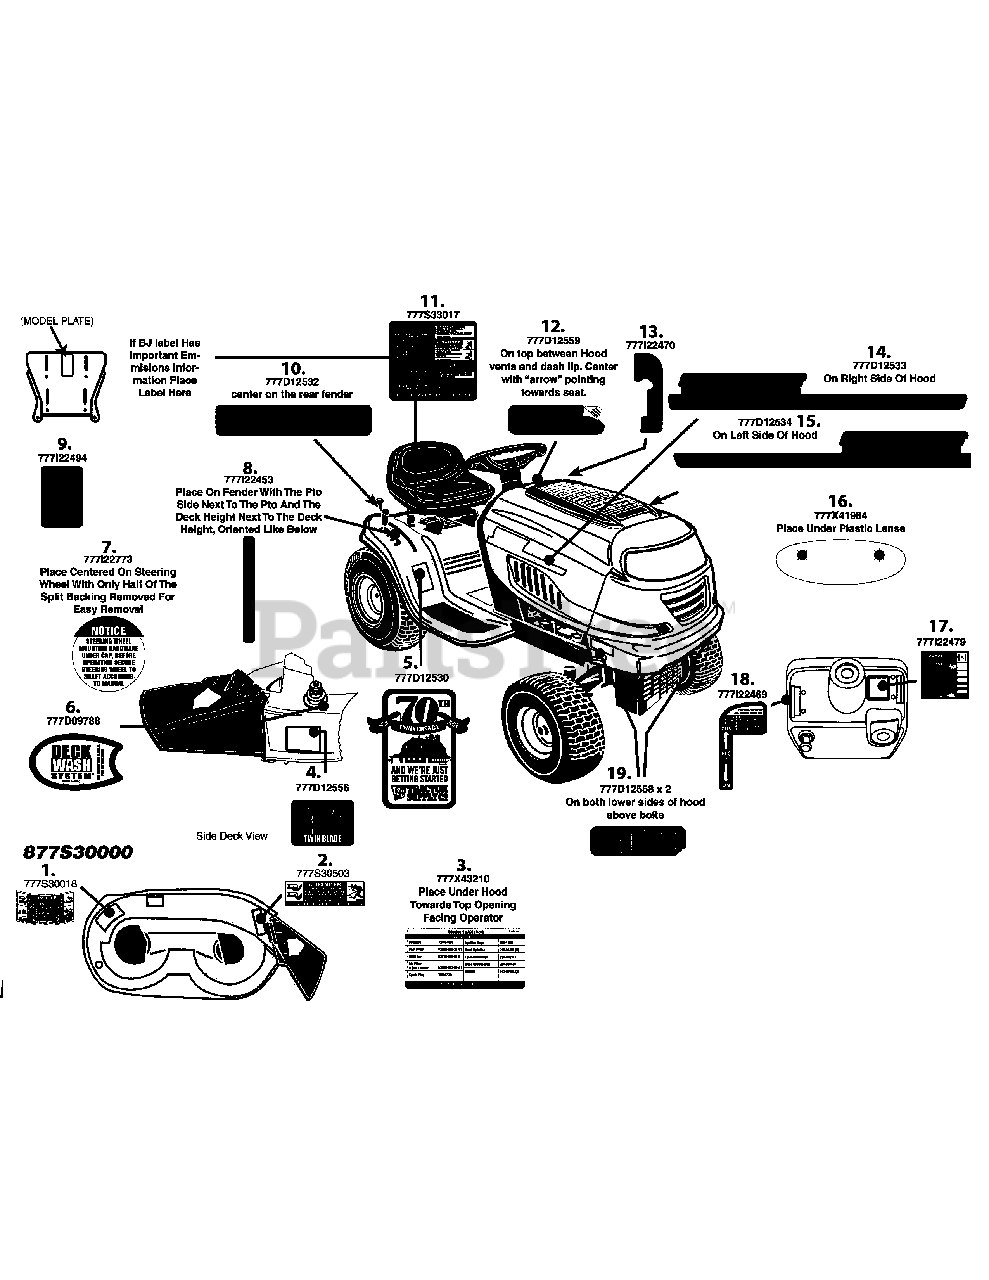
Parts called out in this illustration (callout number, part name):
1	LABEL-DECK SAFETY
2	LABEL-DANGER CHUTE
3	LABEL:RDR:PARTSLIST:13AX795G
4	LABEL:RDR/DK:HUSKEE:42TWIN
5	LABEL:RDR:FEND:70LOGO:TSC
6	LABEL:RIDER:WHITE
7	LABEL-RIDER:SECURE WHEEL
8	LABEL:RIDER LT-5 FENDER
9	LABEL:LT-5 TRANS RELEASE
10	LABEL:RDR:REARFEND:HUSKEE
11	LABEL-LT 5 TRANS COVER NO OCR
12	LABEL:RDR/HOOD/KOHLER:REMOV
13	LABEL:RIDER:LT-5 FENDER HYDRO
14	LABEL-RIDER HOOD RH HUSKEE
15	LABEL-RIDER HOOD LH HUSKEE
16	LABEL:RIDER 1&5 STYLE GRILL
17	LABEL: RIDER LT-5 THRT/CHK
18	LABEL: RIDER LT-5 DASH HYDRO
19	LABEL:RDR/LWRHDSD:HYDRO
